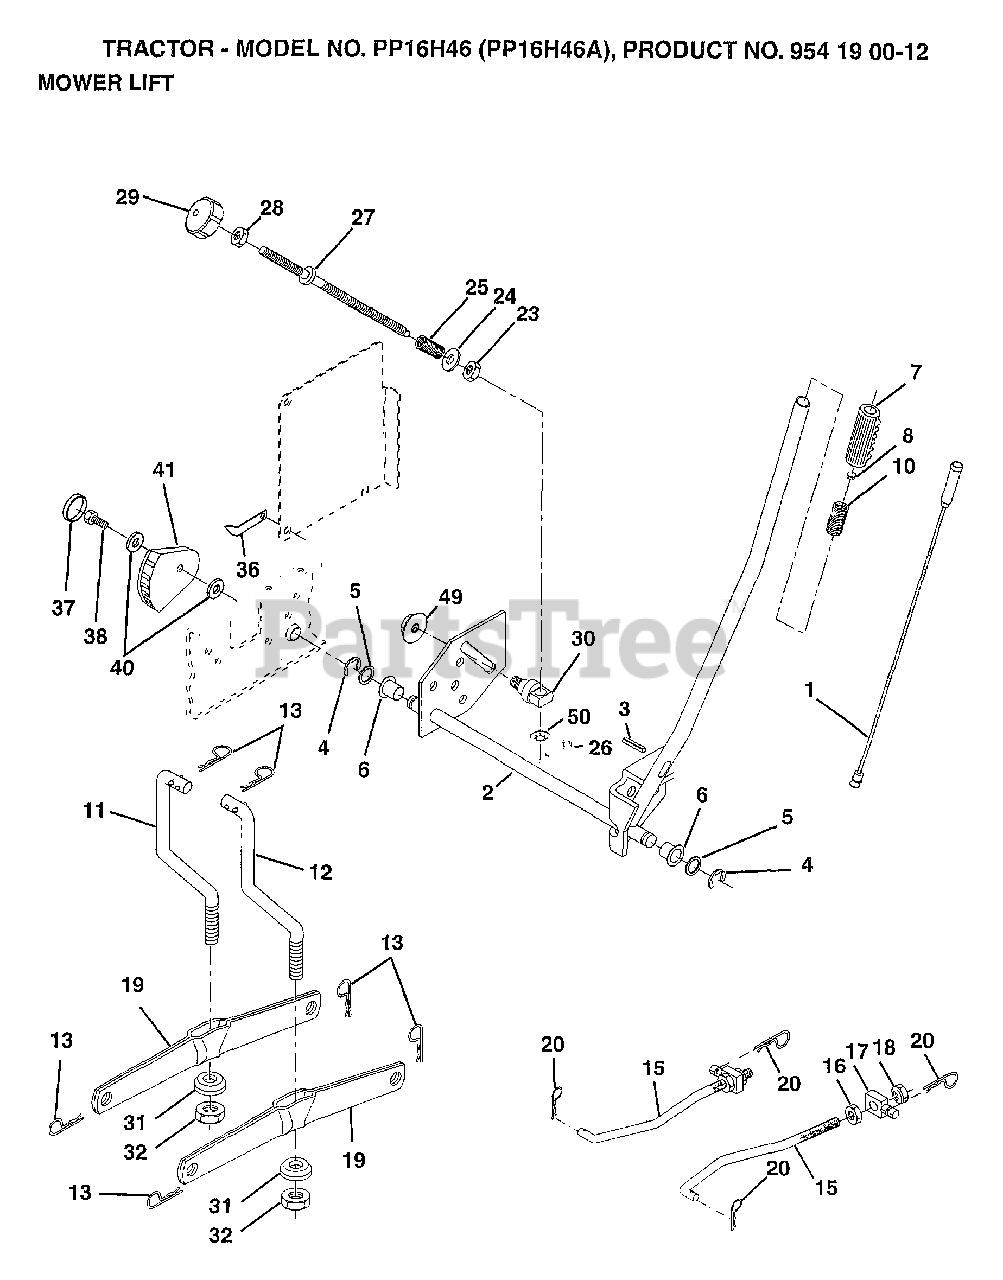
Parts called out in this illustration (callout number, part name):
1	WIRE ASM
2	SHAFT.LIFT.ASM.RH
3	PIN-GROOVE LT
5	WASHER
6	NYLON BEARING
7	GRIP
15	LINK.FRONT
16	NUT
17	TRUNION
18	NUT.LK.W/WSH.1/2.
19	ARM SUSP REAR
20	RETAINER.SPRING
23	NUT T
24	WASHER
25	SPRING T
28	NUT
29	KNOB INF 3/8-16
30	TRUNNION
31	BEARING PVT LH
32	NUT.CROWNLOCK.3/8
36	POINTER-INDICAT
37	"PLUG,HOLE"
38	SCREW
40	WASHER
41	INDICATOR HEIGHT
49	NUT.HXFLG.LOCK.
50	NUT PUSH M
